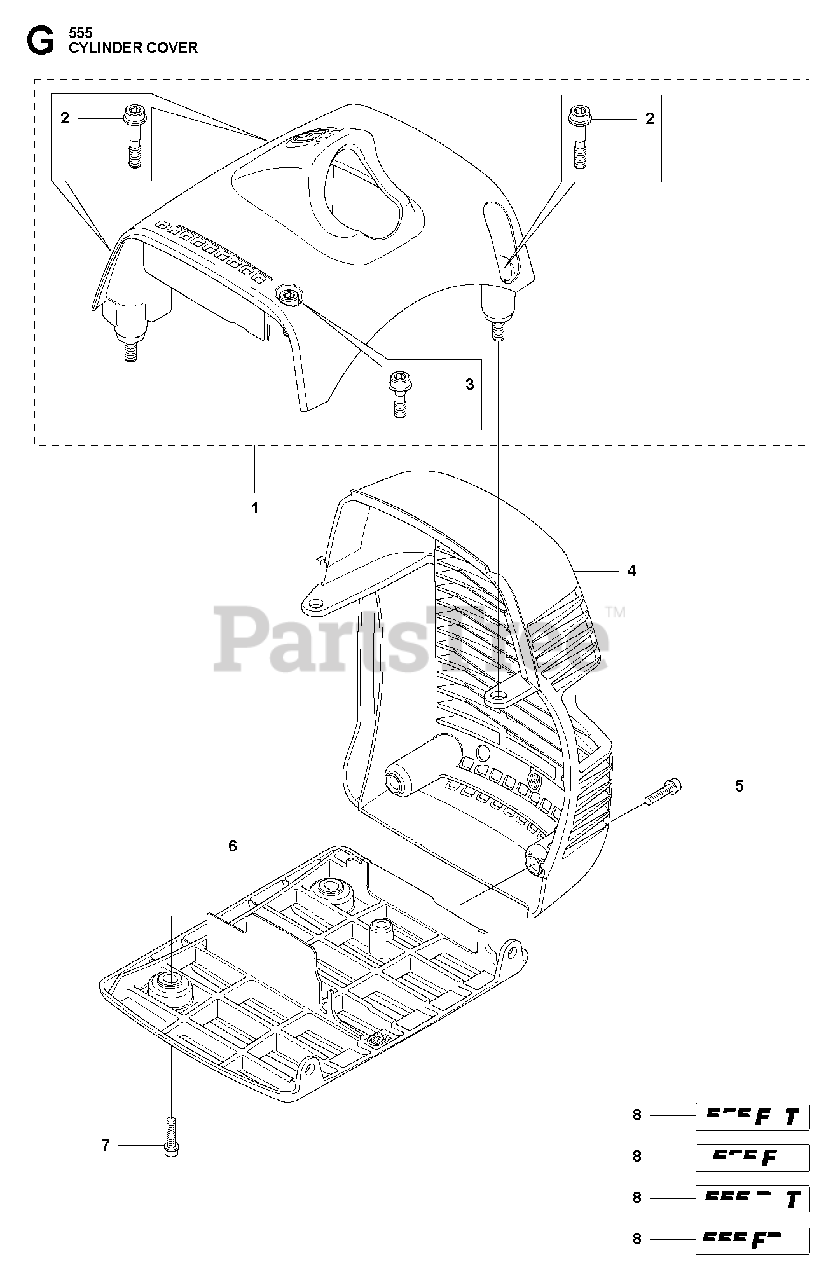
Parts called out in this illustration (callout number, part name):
1	CYLINDER COVER ASSY SPARE PAR
2	SCREW IHSCFMO
3	SCREW IHSCFMO
4	HEAT PROTECTOR
6	PROTECTIVE COVER ASSY HUSQ
8	LABEL CYLINDER COVER 555 FXT
8	LABEL CYLINDER COVER 555 FX
8	LABEL CYLINDER COVER 555 RXT
8	LABEL CYLINDER COVER 555 FRM
